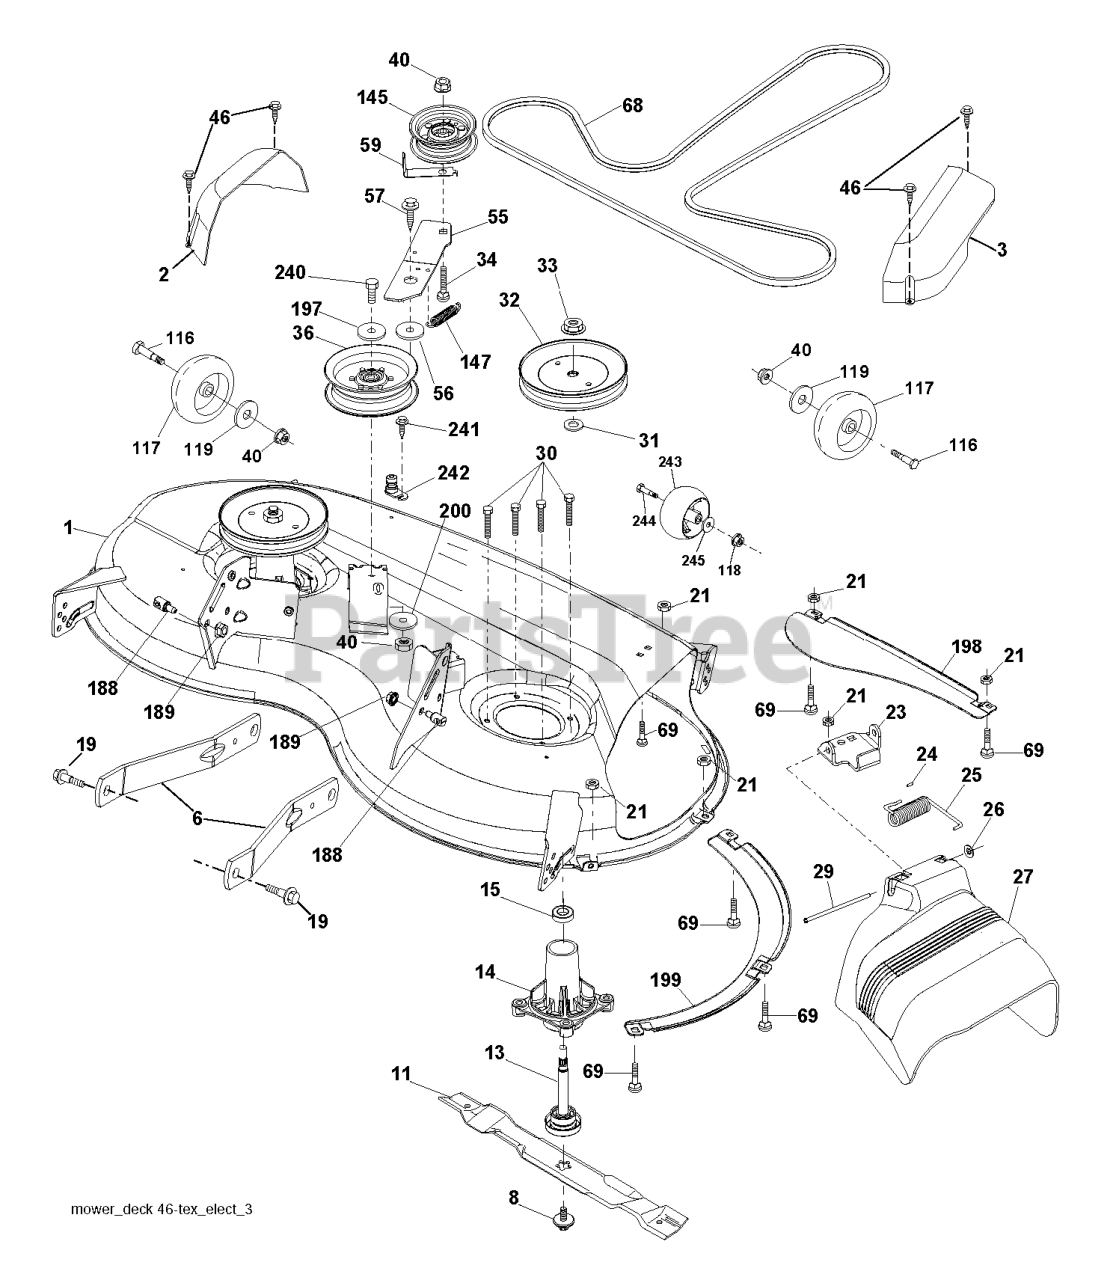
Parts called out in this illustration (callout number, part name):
2	COVER.MANDREL.LH.46"
3	COVER.MANDREL.RH.46"
6	ARM.SUSPENSION.MOWER.R
8	BOLT.WASHER.ASM.7/16-2
11	BLADE.MOWER.46".HI.LIFT
13	SHAFT.ASM.MDRL.N/GREASE.38
14	RP.HOUSING.MANDREL.4PT.
19	BOLT.SHOULDER
21	LOCKNUT
23	BRKT.DEFLECTOR.38"2005+
24	CAP-SLEEVE LT
25	SPRING.TORSION.DEFLECT
26	NUT PUSH M
27	SHIELD.DEFLECTOR.MOWER.46"BLAC
29	ROD.HINGE
30	SCREW, WASHER HEAD
31	WASHER.SPACER.MANDREL
32	PULLEY.MANDREL.5.438.PD
33	NUT.FLANGE.LOCK.TOP
34	BOLT.3/8-16X1.50
36	PULLEY.IDLER.2006
40	NUT LOCK FLG 3/8-16 UNC
46	SCREW.1/4-20X5/8
56	SPACER.RETAINER
57	SCREW 3/8-16X1
59	GUARD, BELT
68	V-BELT
69	BOLT
116	BOLT.SHOULDER.3/8-16X3-5/8.
117	RP WHEEL. GUAGE RALLY
118	LOCKNUT
119	WASHER
145	PULLEY.IDLER.48"PRIMARY
147	SPRING.MOWER.DRIVE.ELECTRIC
188	STUD.FASTNER.W/ANTI-ROTATE
189	NUT LOCK HEX FLANGE 5/16-18
197	WASHER
198	BAFFLE CENTER FRONT
199	BAFFLE FRONT RH
200	WASHER.13/32 X 1 X 1/2.11GUARD
240	BOLT-HEX EAK
241	SCREW.TT.#10-32X.5.3/8.FLANGE
242	PORT.WASHOUT
243	WHEEL.GAGE.HALF.SPOKED
244	BOLT.SHLD."A"2.41."B"1.66
245	WASHER.5/16.FLAT.STE.STD.
